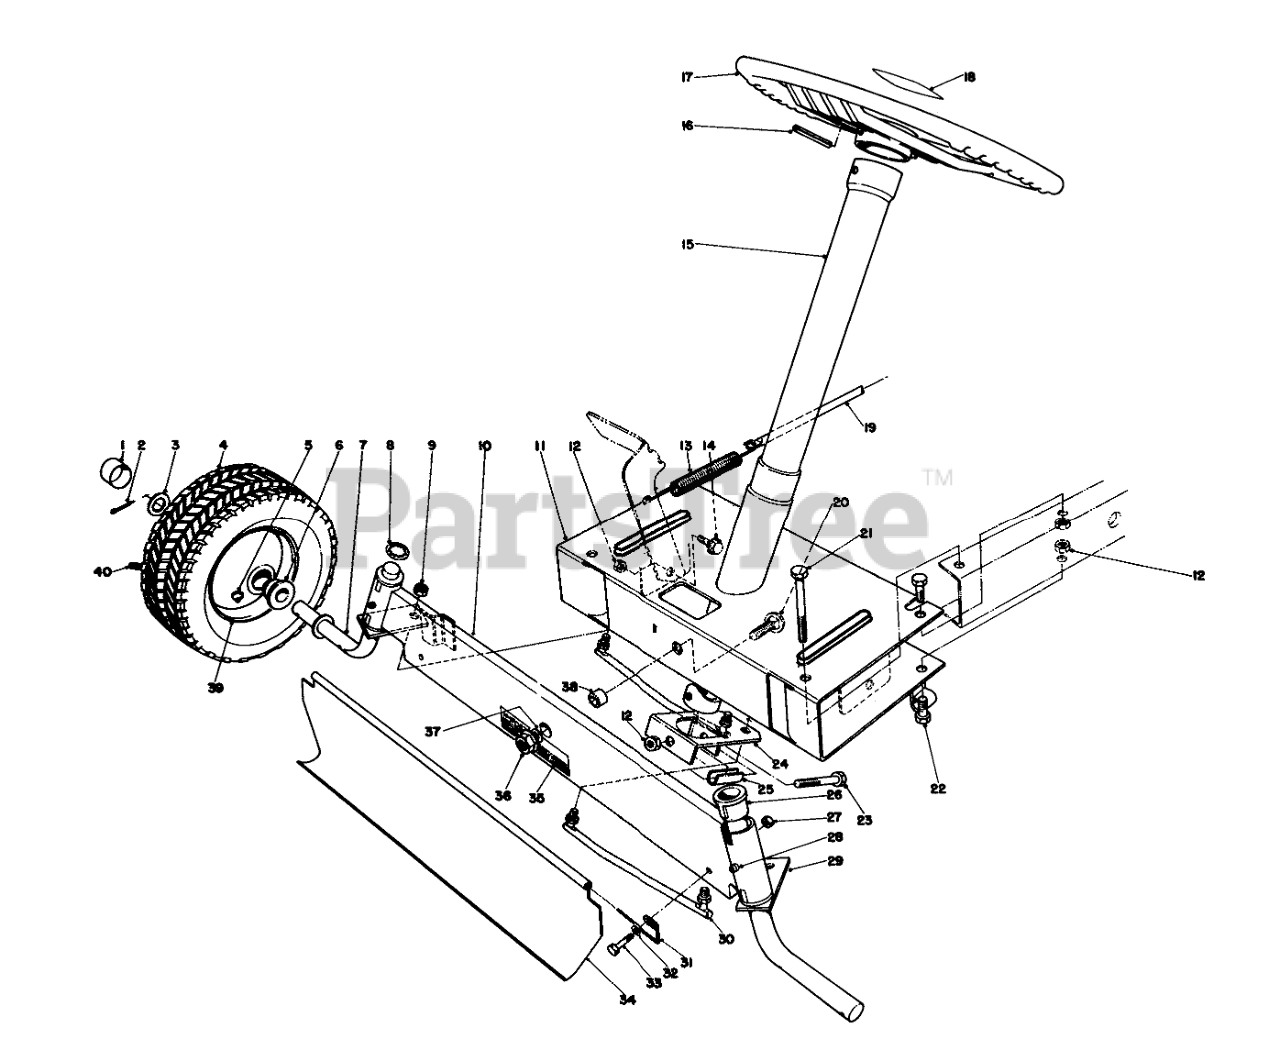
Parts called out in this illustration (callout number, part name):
1	Hub Cap
2	PIN-COTTER
3	WASHER-FLAT
4	Tire Turf King
5	FITTING-GREASE
6	BUSHING
7	SPINDLE WA RH
8	RING-RETAINING
10	Front Axle
11	Front Frame
12	NUT-LOCK, CONE
13	BRAKE TENSION SPRG O
14	SCREW-SHOULDER
15	Steering Tube
16	PIN-ROLL
17	Steering Wheel
18	Decal
19	Brake Rod
20	SCREW-CARR
21	SCREW-HH
22	SCREW-HH
23	SCREW-HH
24	Lever Steering
25	Spacer-Steering Tube
26	BUSHING
28	Fitting-Grease
29	Spindle L.H.
30	TIE ROD ASM
31	Hanger-Safety Shield
32	WASHER-FLAT
33	SCREW-HH
34	Safety Shield
35	Decal-Instruction
36	NUT-HF
37	WASHER-THRUST
38	FRONT AXLE SPACER
40	STEM-VALVE
